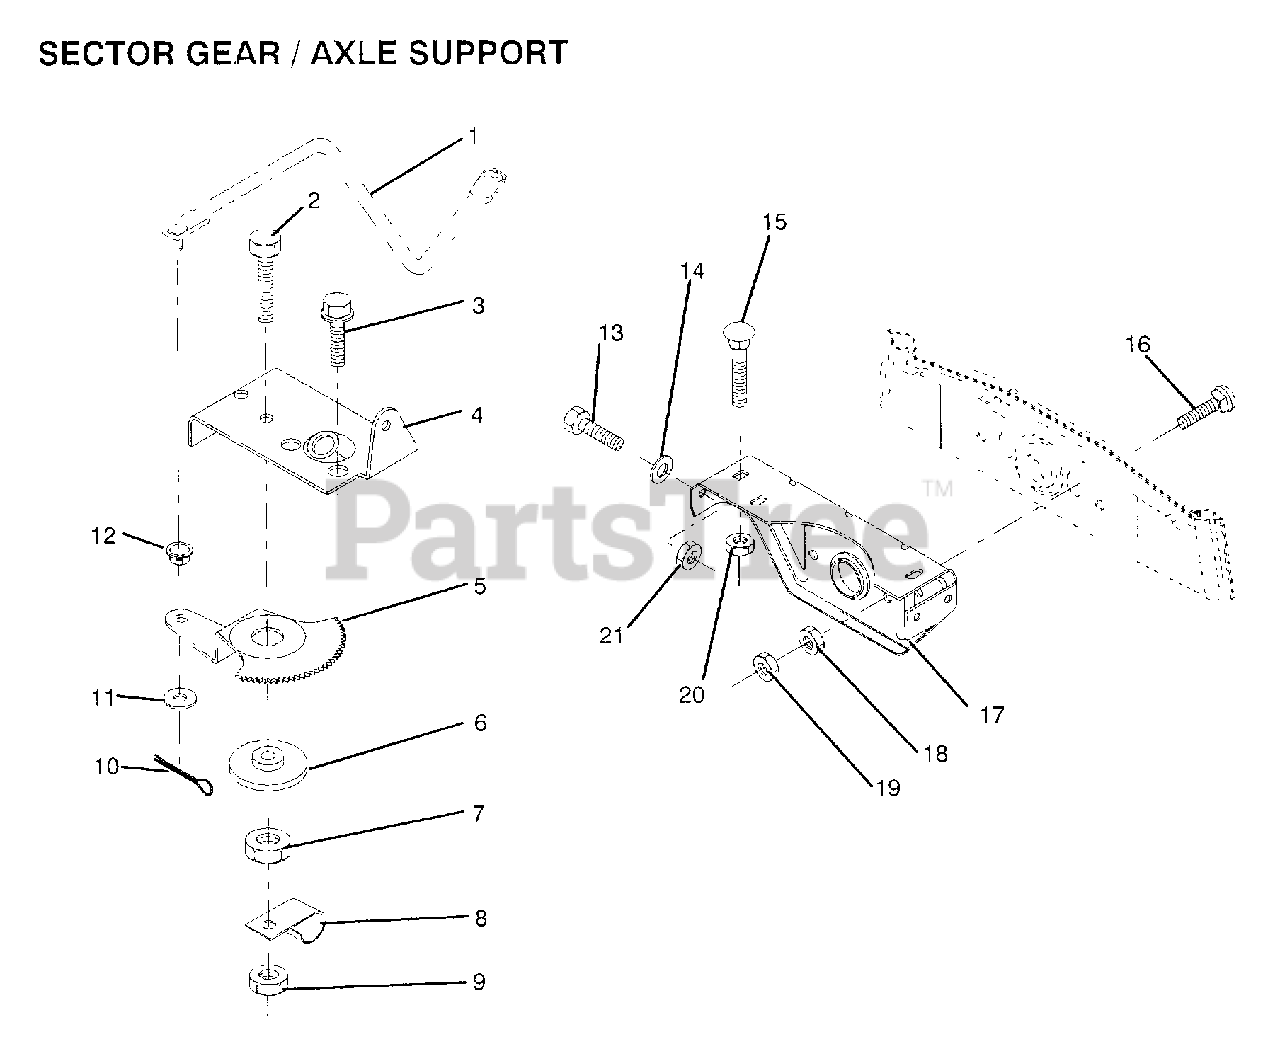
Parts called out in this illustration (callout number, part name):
2	"BOLT,HEX"
3	SCREW LT
4	"PLATE,STR SUPT"
5	GEAR SECTOR
6	BUSHING
7	NUT
8	CLIP INSULATOR
9	NUT LTV
10	COTTER PIN
11	WASHER
12	BUSHING.DRAGLINK
13	BOLT
14	WASHER
15	BOLT
16	BOLT
17	"SUPT,FRT AXLE"
18	NUT.HEX.3/8-16UNC
19	LOCKNUT
